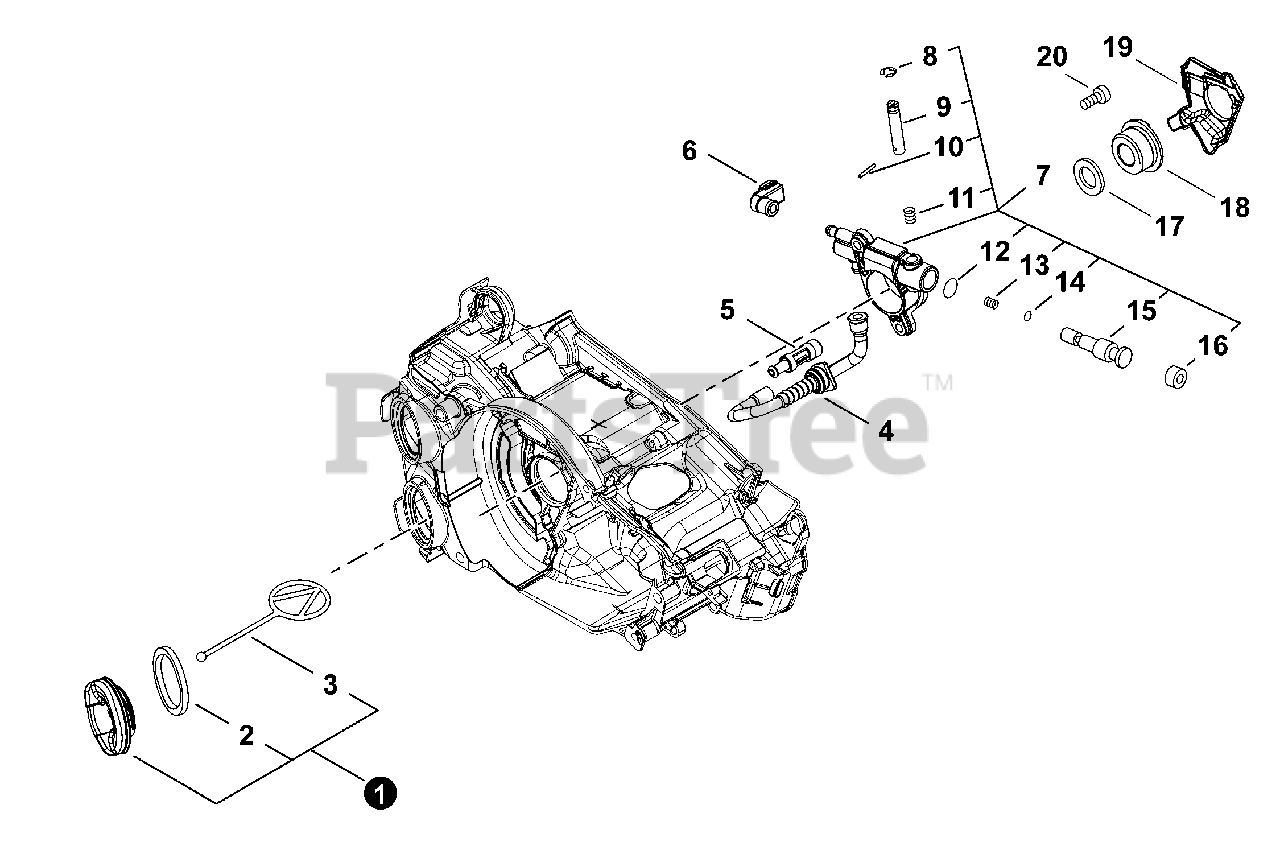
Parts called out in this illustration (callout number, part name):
1	CAP ASSY, OIL
2	GASKET, CAP
3	CONNECTOR, CAP L= 60 MM
4	PIPE, OIL
5	FILTER ASSY, OIL
6	PIPE, OIL OUTLET
7	AUTO-OILER ASSY
9	ADJUSTER, OILER
10	PIN, SPRING
15	PLUNGER ASSY
16	CAP, OIL PUMP
17	WASHER 10.5×17.4×1.8
18	GEAR, WORM
19	COVER, OILER
20	BOLT, TORX 4×12
